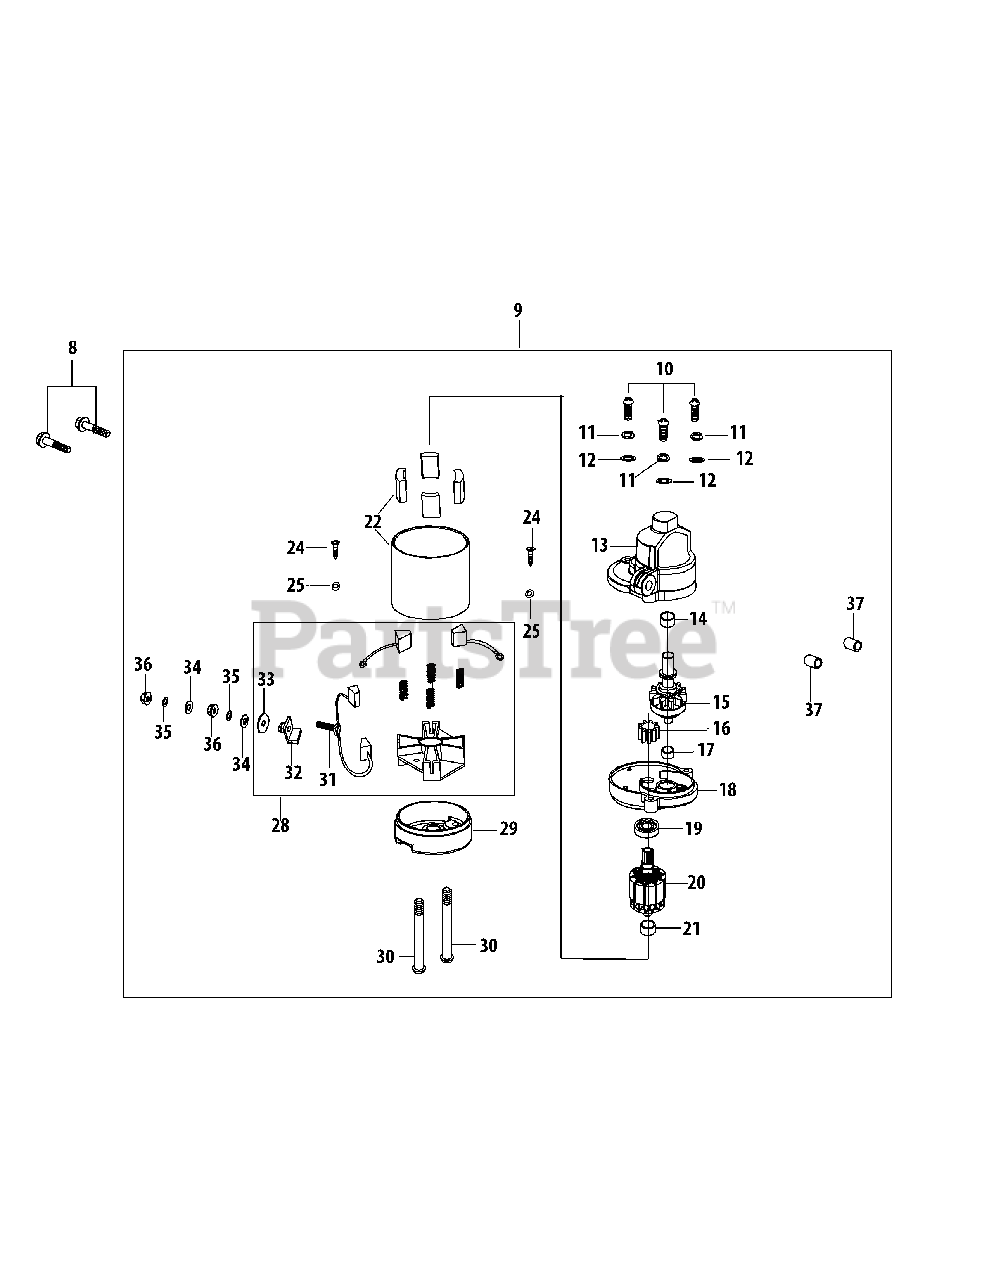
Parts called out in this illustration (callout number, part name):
8	Bolt M8×40
9	Starter Assembly
10	Screw M5×25
11	Lock Washer 5
12	Plain Washer 6
13	Electrical Starter Front Cover
14	Bearing
15	Pinion/Clutch Assembly
17	Bearing
18	Pinion Cover
19	Bearing 6001Zz
20	Starter Armature
21	Bearing
22	Starter Housing Assembly
25	Lock Washer
28	Brush Assembly
29	Electrical Starter Back Cover
30	Bolt M6×100
31	Bolt M6×30 Assembly
32	Waterproof Washer
33	Insulation Washer
34	Plain Washer 6
35	Lock Washer 6
36	Nut M6
37	Dowel Pin 10×14
